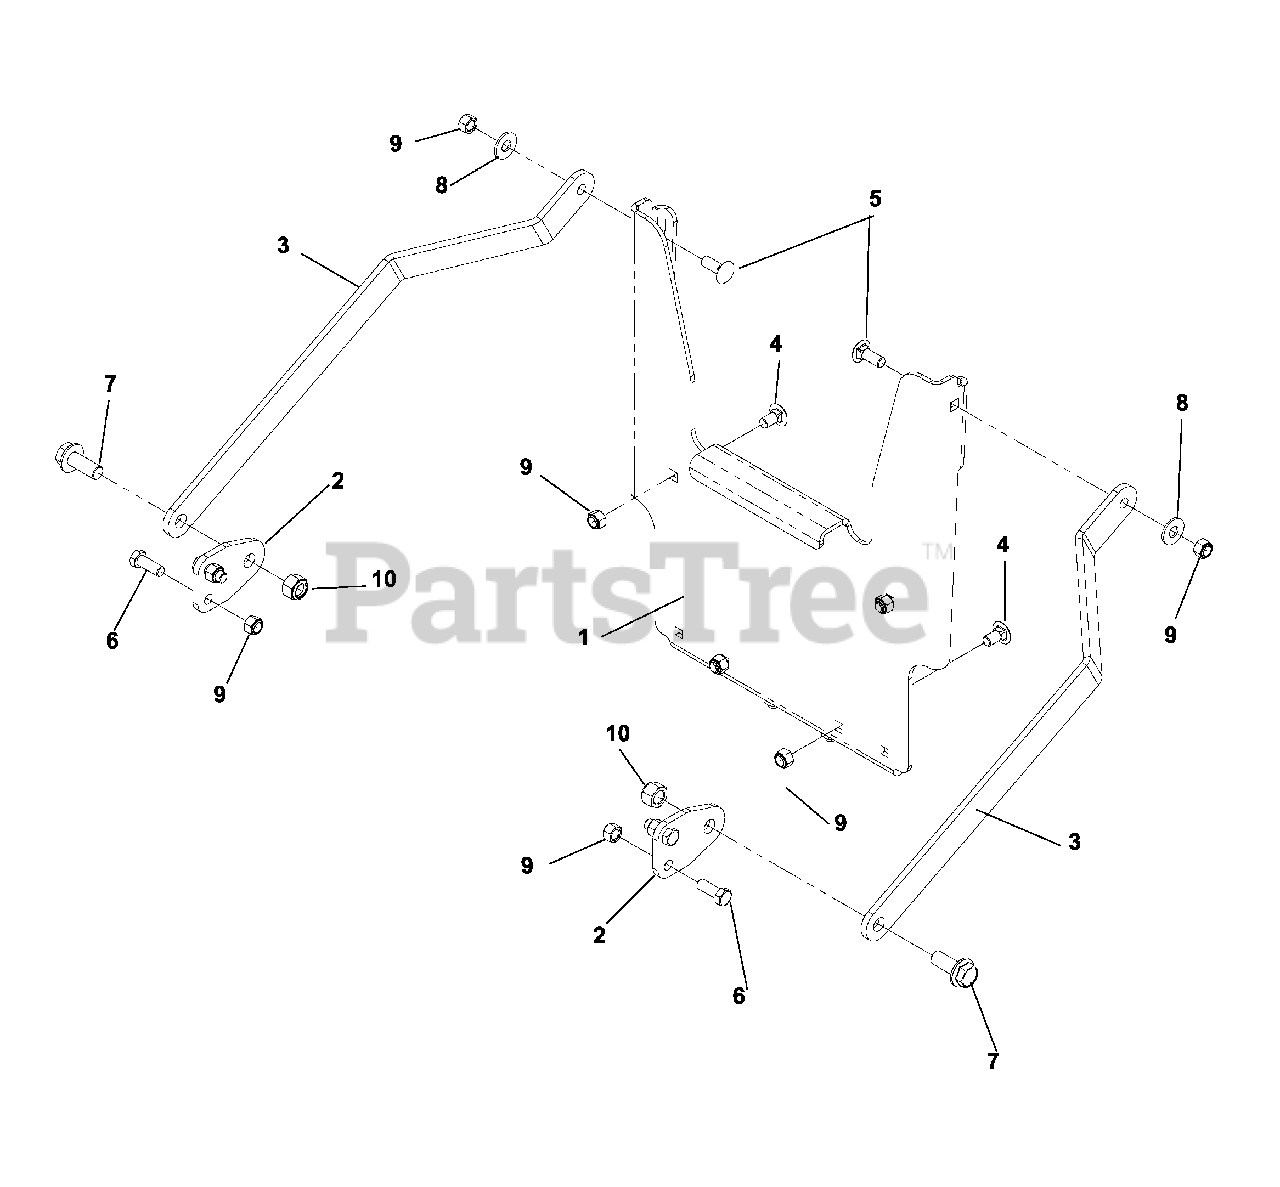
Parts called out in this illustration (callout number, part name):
1	PLATE, MOUNT, PAINTED
2	SUPPORT BRACKET
4	RHSNB 3/8-16 X 3/4 GR5 ZD
5	RHSNB 3/8C X 1
6	HCS 3/8C X 1
7	HCS 1/2C X 1 1/4 SERRATED HEAD
8	WASHER 3/8 FLAT
9	NUT 3/8-16 NYLOC
10	NUT 1/2-13 HEX NYLOC ZD
